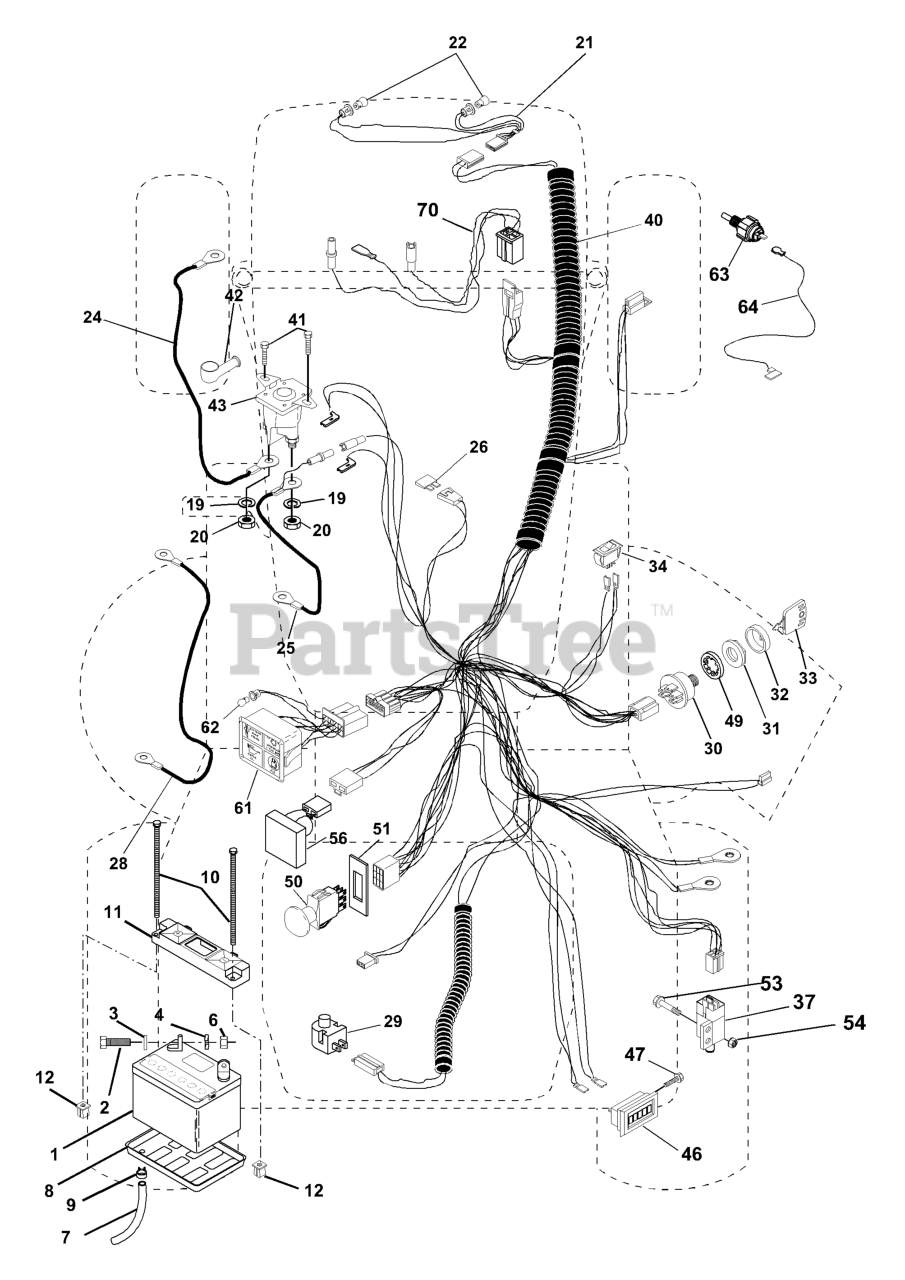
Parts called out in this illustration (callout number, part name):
1	BATTERY
2	BOLT.HEX.1/4.X.3/4.DICHROMATE
3	LOCKWASHER
4	WASHER
6	NUT
7	PLASTIC TUBE
8	BATTERY TRAY T
9	HOSE CLAMP T
10	BOLT 1/4-20 X 7.5
11	HOLDDOWN, BATTERY, DASH MOUNT
12	NUT, PUSH NYLON 1/4" BATTERY
19	LOCKWASHER
20	NUT
21	HARNESS LIGHT SOCKET
24	CABLE-BATTERY YTV
25	CABLE, BATTERY
28	CABLE T
29	RP.SWITCH.PLUNGER.NC.GRAY
30	IGNITION SWITCH
31	NUT, IGNITION
32	COVER SWITCH KEY
33	KEY MLD GEN DELTA
37	SWITCH INTERLOCKT
40	Harness Ign.
41	SCREW
42	TERMINAL COVER
43	SOLINOID
46	HOUR METER T
47	Screw #10-24 x 1/2
49	Washer, Lock Internal Tooth 5/8
50	SWITCH-PTO
51	FRAME RETAINING RING
53	SCREW **
54	Nut Keps #10-32
56	SENSOR LOW VOLTAGE
61	LIGHT PACKAGE
62	BULB LIGHT T
63	SWITCH, OIL PRESSURE
70	ENGINE HARNESS
